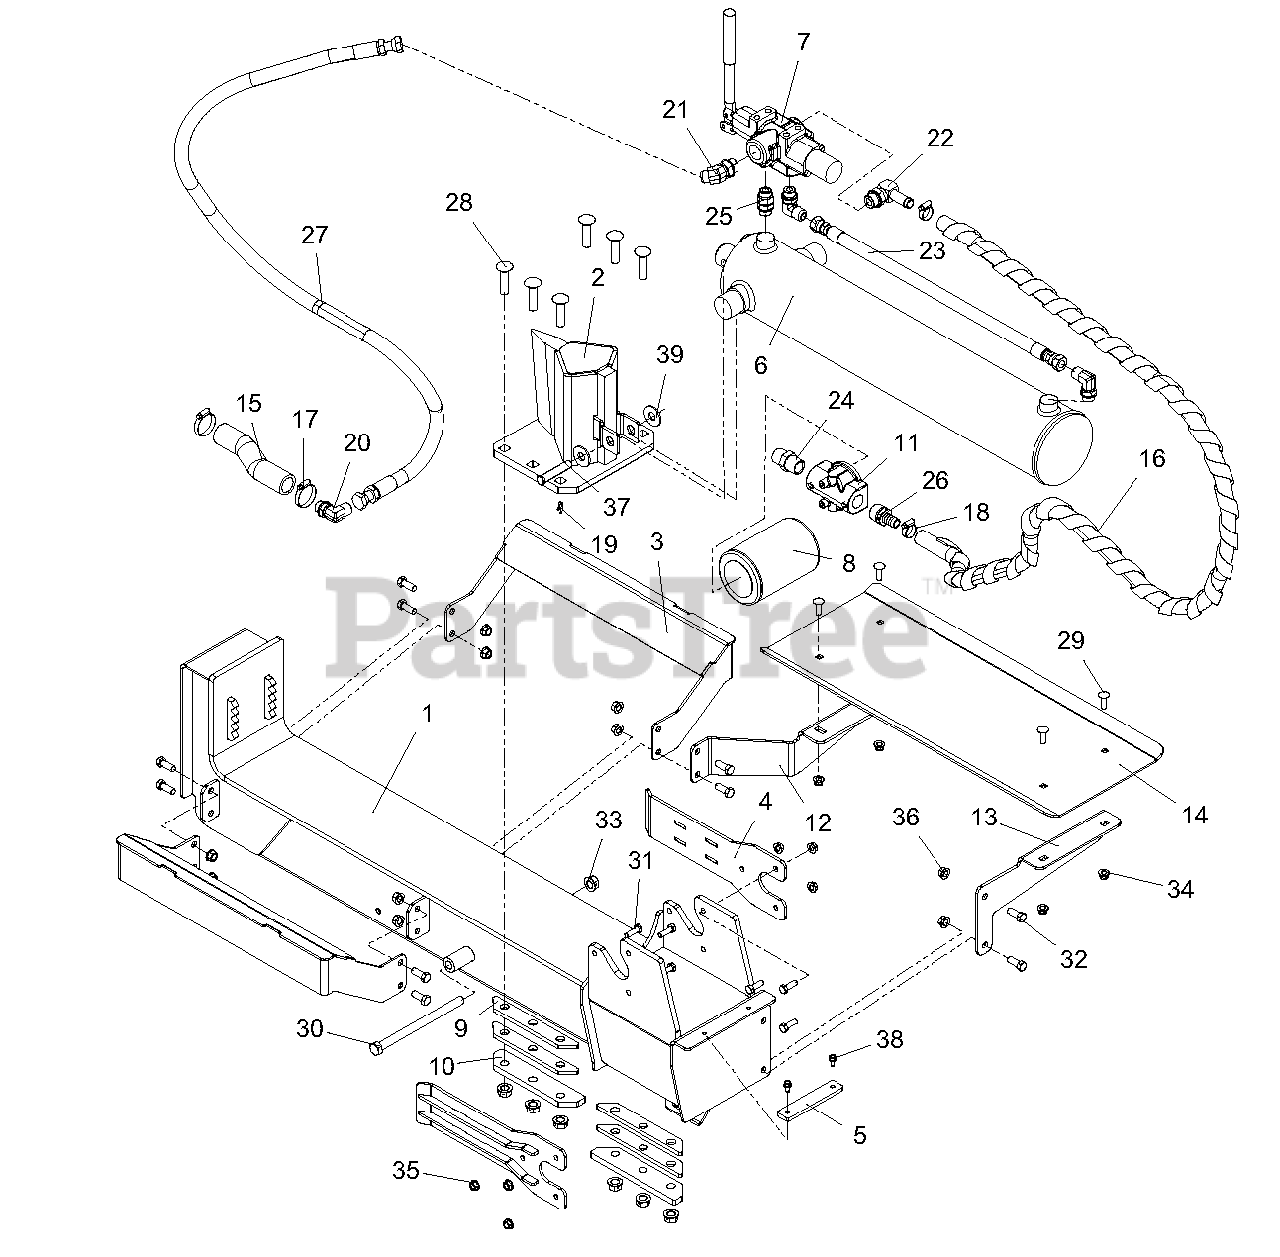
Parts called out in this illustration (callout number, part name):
1	WLDMT, BEAM - 27&34T SPLITTER
2	WLDMT, WEDGE - SPLITTER
3	WLDMT, CRADLE - LOG SPLITTER
4	PLATE, STRIPPER-RED
5	SPCR, CYLINDER
6	CYLINDER, SPLITTER - 4.5"
7	VALVE, CONTROL - SPLITTER
8	FILTER, OIL - W/BYPASS
9	SPCR, WEDGE
10	RETAINER, WEDGE-BLACK
11	HEAD, FILTER - 3/4 NPT BYPASS
12	BRKT, REAR - WORK TABLE
13	BRKT, FRONT - WORK TABLE
14	TABLE, WORK - LOG SPLITTER
15	HOSE, HYD SUCTION, 6.75"
16	HOSE, HYD - RETURN 74"LG
17	CLAMP, HOSE 1.50 X .81 X 1.42
18	CLAMP, .88 DIA HOSE
19	CLIP, SPRING
20	FTG, HYD. 2501-8-8
21	FTG, HYD. 6802-8-10
22	FTG, HYD. 4601-10-10
23	HOSE, ASSY, 8M3K-8FJX-8FJX-22
24	FITTING, HYD 5404-12-12
25	FTG, HYD - STR 08MAORB-08MORB
26	FTG, HYD 3/4"NPT X 5/8" ID HOSE BARBED
27	HOSE, HYD 8M3K-8FJX-58
28	@BLT-RDHDSQNK .50-13X2.00 G8 Y
29	BLT-RDHDSQSHNK .31-18X1.00 G5YWZC
30	BLT-HEX .50-13X7.50 GR5 YWZC
31	BLT-HEX .31-18X1.00 GR5 YWZC
32	BLT-HEX .38-16X1.00 GR5 YWZC
33	NUT-LK-CTR-FLG .50-13 YWZC
34	NUT-LK-NYL-FLG .31-18 YWZC
35	NUT, LK-TOP-FLG .312-18 YWZC
36	NUT, LK-TOP-FLG .38-16 YWZC
37	PIN-CLEV .494X2.50X2.27 YWZC
38	SCR-TAP .25-20X.50 HWH TR YWZ
39	WSHR-FL-STL .563X1.38X.109YWZC
